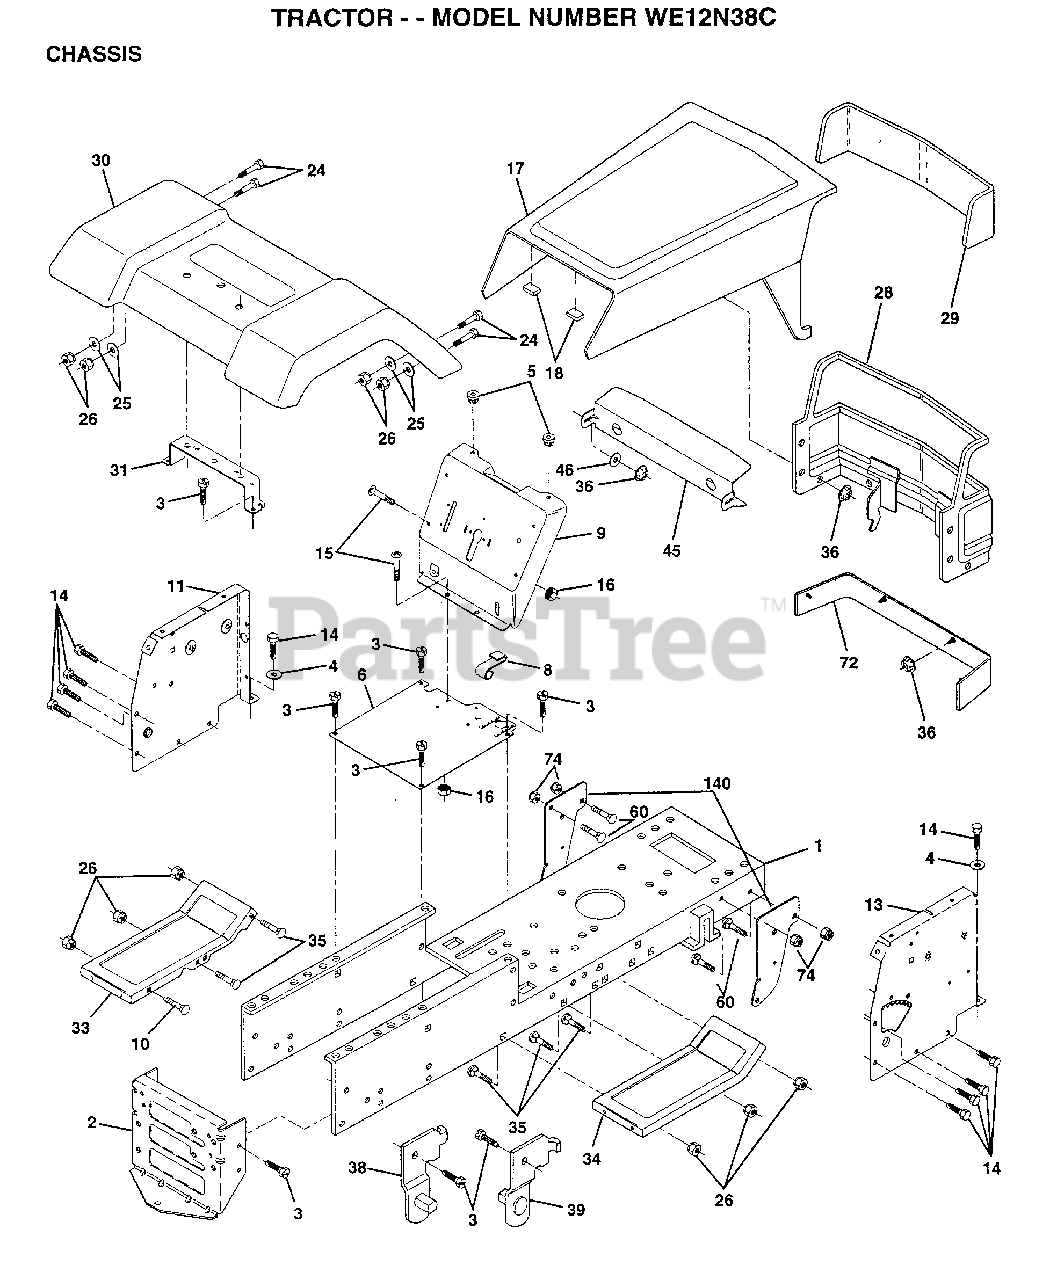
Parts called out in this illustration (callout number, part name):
1	CHASSIS WLDMT 11G
3	SCREW
4	WASHER
8	"CLIP,INSULATOR"
9	DASH.SLKSC.LT.1PC
11	PANEL.DASH.LH.
13	HOOD.W/SD.PNLS.LT
14	SCREW LT
15	SCREW
17	HOOD.W/SD.PNLS.LT
24	BOLT
25	WASHER
26	NUT
28	GRILLE.RALLY.BAR.
31	BRKT FENDER
33	FOOTREST.LH.PERF.
34	FOOTREST.RH.PERF.
35	BOLT
36	PAL NUT LT
38	BRACKET ASM LH
39	BRACKET ASM RH
46	RETAINER
60	BOLT
72	STRAP.GRILLE.PNT.
